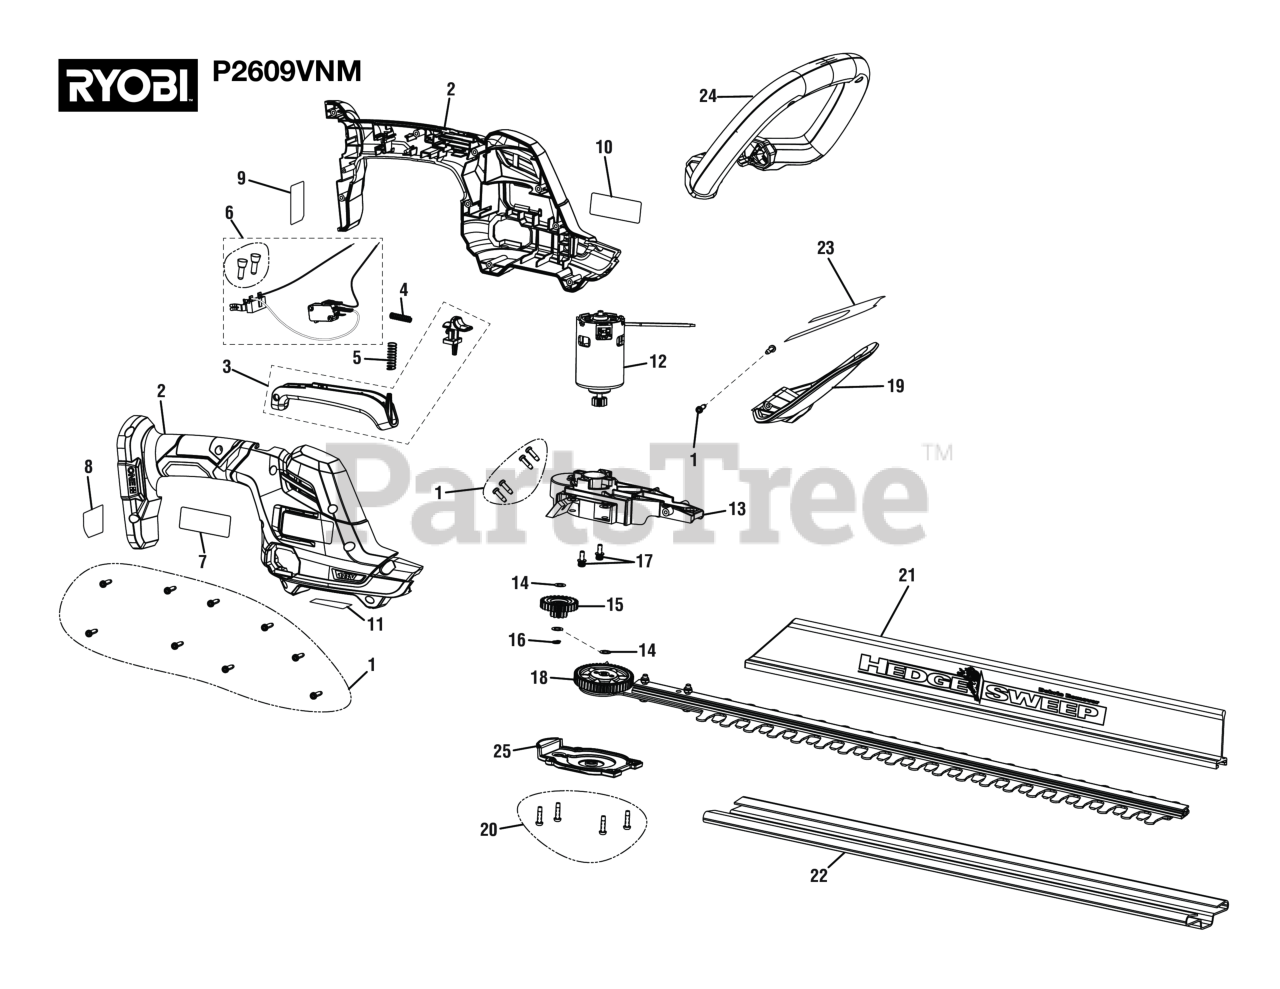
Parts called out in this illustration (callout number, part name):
1	Screw (M4 x 14 mm, T15 Torx Pan Hd.))
2	Housing Assembly
3	Trigger and Lockout Button Assembly
4	Spring, Lockout Button, Dia. 4.6, Soring
5	Compression Spring
6	Wiring Harness
7	Data Label
8	Battery Statement Label
10	Logo Label
11	Warning Label (SP)
12	Motor and Pinion Assembly
13	Gear Box Base
14	Washer (M6, ID6.2 x 11OD x 0.3t)
15	Center Gear
16	RETAINING RING (EXTERNAL)
17	Screw w/Washer (#10-24 x 15 mm, Pan Hd)
18	Blade Assembly
19	Guard Assembly
20	Screw (M4 x 16 mm, Pan Hd.)
21	Hedge Sweep
22	Blade Shield
23	Icon Warning Label (ENG/FR)
24	Front Handle Assembly
25	Gear Box Cover
